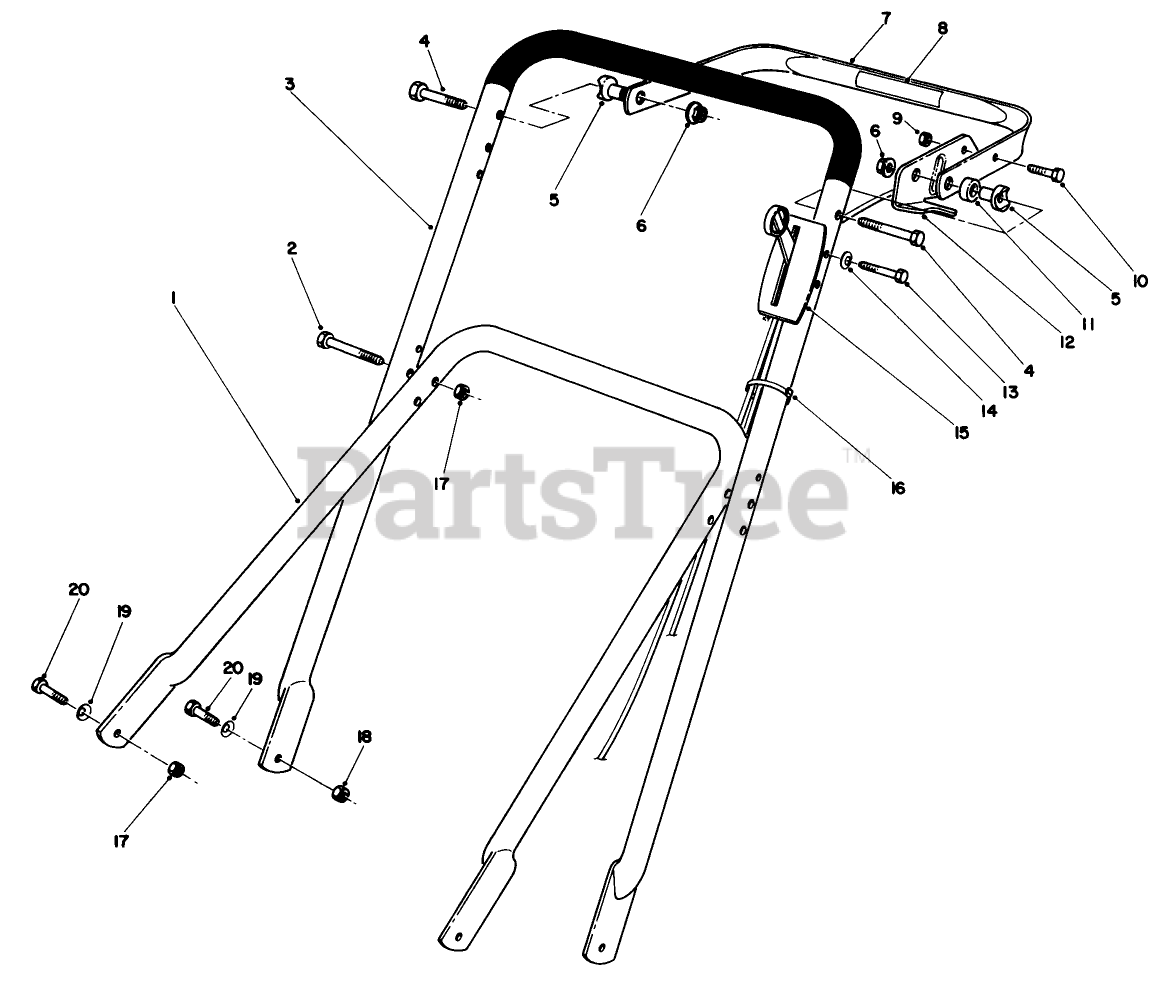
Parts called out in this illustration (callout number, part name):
2	SCREW-HH
4	SCREW-HH
5	SPACER-SUPPORT
6	NUT-HF
9	NUT-LOCK, NI
10	SCREW-HH
11	SPACER-NYLON
13	SCREW-HH
14	WASHER
16	TIE-CABLE
17	NUT-LOCK, NI
18	NUT-LOCK, NI
19	WASHER-BELLEVILLE
20	SCREW-HH
